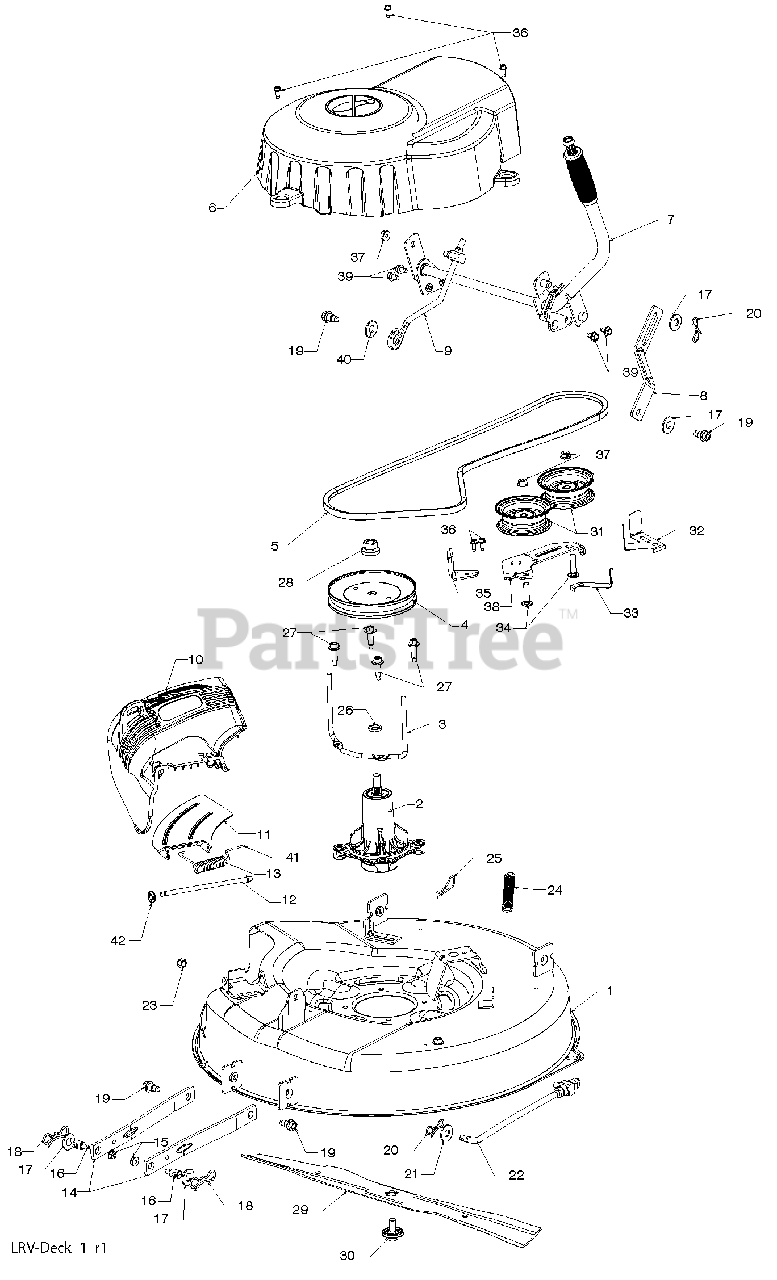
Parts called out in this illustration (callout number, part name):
1	DECK, 26"
2	MANDREL ASM
3	KEEPER, BELT
4	PULLEY, MANDREL
5	BELT
6	COVER, MANDREL
7	LIFT ASM, DECK
8	LINK, DECK LIFT
9	LINK, ADJUSTABLE
10	DEFLECTOR
11	SUPPORT, DEFLECTOR
12	ROD, HINGE
13	SPRING, TORSION
14	ARM, MOWER SUPPORT
15	NUT, LOCK
16	STUD
17	WASHER
18	PIN
19	BOLT, SHOULDER
20	PIN
21	WASHER, 17/32 X 1 3/16
22	LINK, DECK
23	NUT, LCK 3/8-16
24	SPRING, DECK
25	PIN
26	SPACER, MANDREL
27	BOLT, MANDREL
28	NUT, LOCK
29	BLADE
30	BOLT, BLADE
31	PULLEY, IDLER
32	GUARD, IDLER
33	KEEPER, BELT IDLER
34	BOLT, 3/8-16 X 1 1/2
35	ARM, BRAKE
36	SCREW, 1/4-20 X 5/8
37	NUT, 3/8-16 FLANGE
38	ARM, IDLER
39	BOLT, 5/16-18 X 1/2
40	WASHER, 16 GA.
41	CAP, SLEEVE
42	NUT, PUSH
